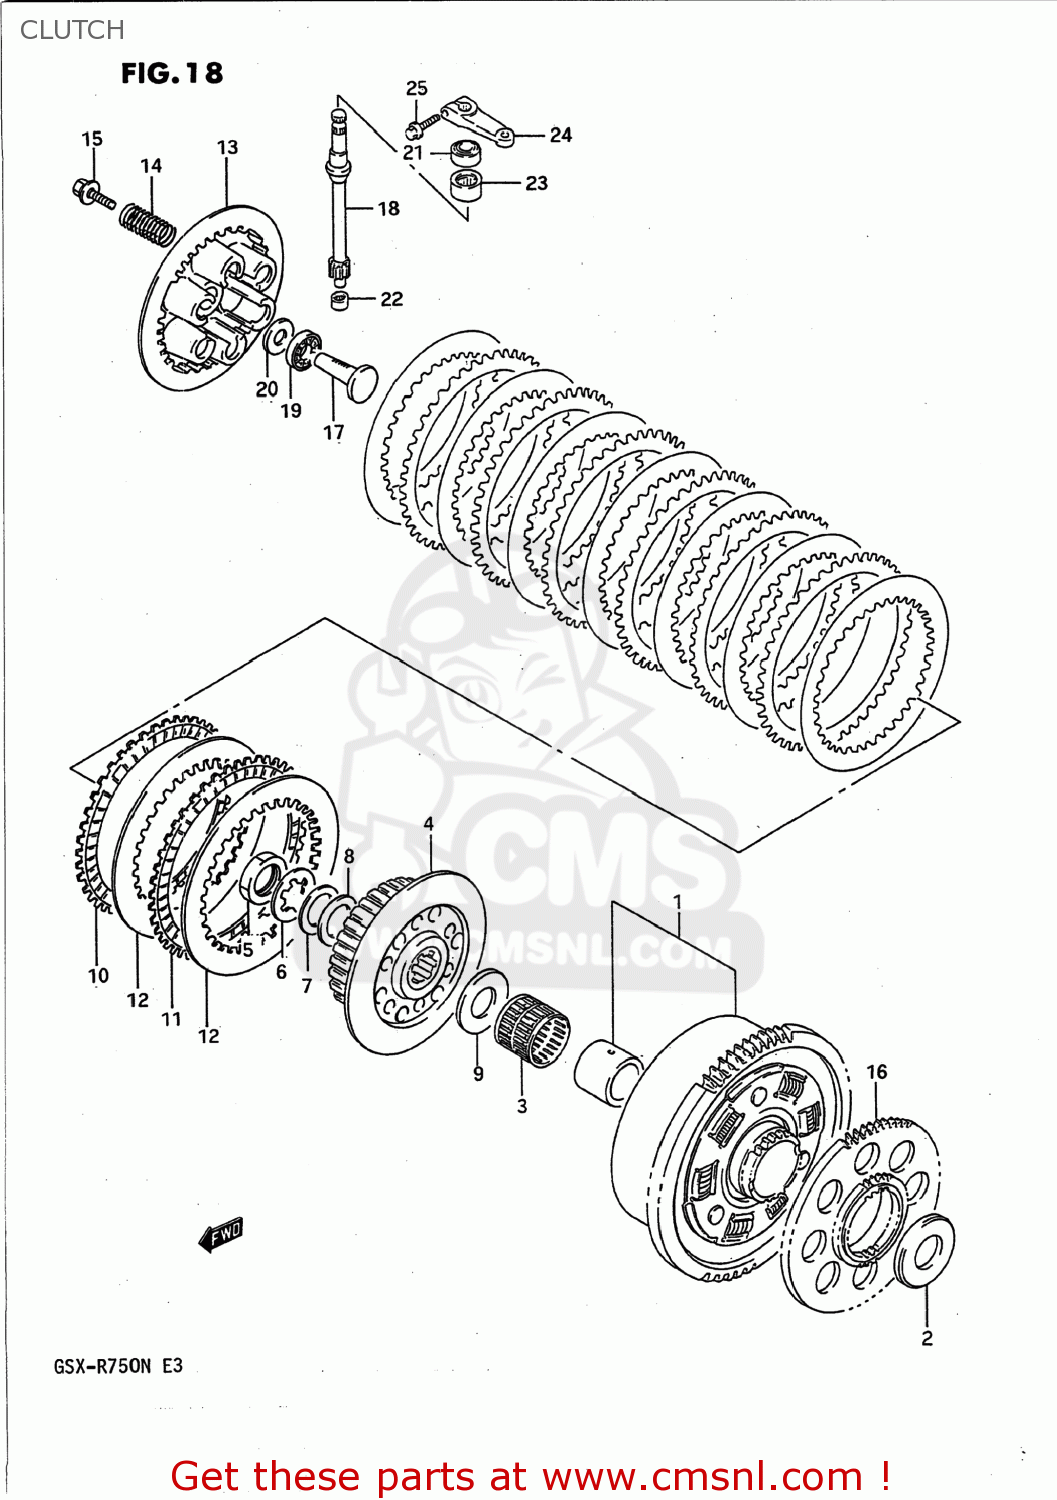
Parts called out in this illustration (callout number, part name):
1	GEAR ASSEMBLY,PRIMARY DRIVE
2	WASHER(25X54X2.5)
3	BEARING(35X40X35.8)
4	HUB,CLUTCH SLEEVE
5	NUT
6	WASHER,LOCK
7	WASHER
8	SHIM
9	WASHER(25X50X2.5)
10	PLATE,CLUTCH DRIVE (NAS)
11	PLATE,CLUTCH DRIVE NO.2 (NAS)
12	PLATE,CLUTCH DRIVEN (NAS)
13	DISC,CLUTCH PRESSURE
14	SPRING
15	BOLT(6X25)
16	GEAR,GENERATOR DRIVE
17	RACK,CLUTCH RELEASE
18	PINION,CLUTCH RELEASE
19	BEARING(15X28X2)
20	WASHER
21	OIL SEAL
22	BEARING 10X14X10
23	BEARING(15X22X12)
24	ARM,CLUTCH RELEASE
25	BOLT
